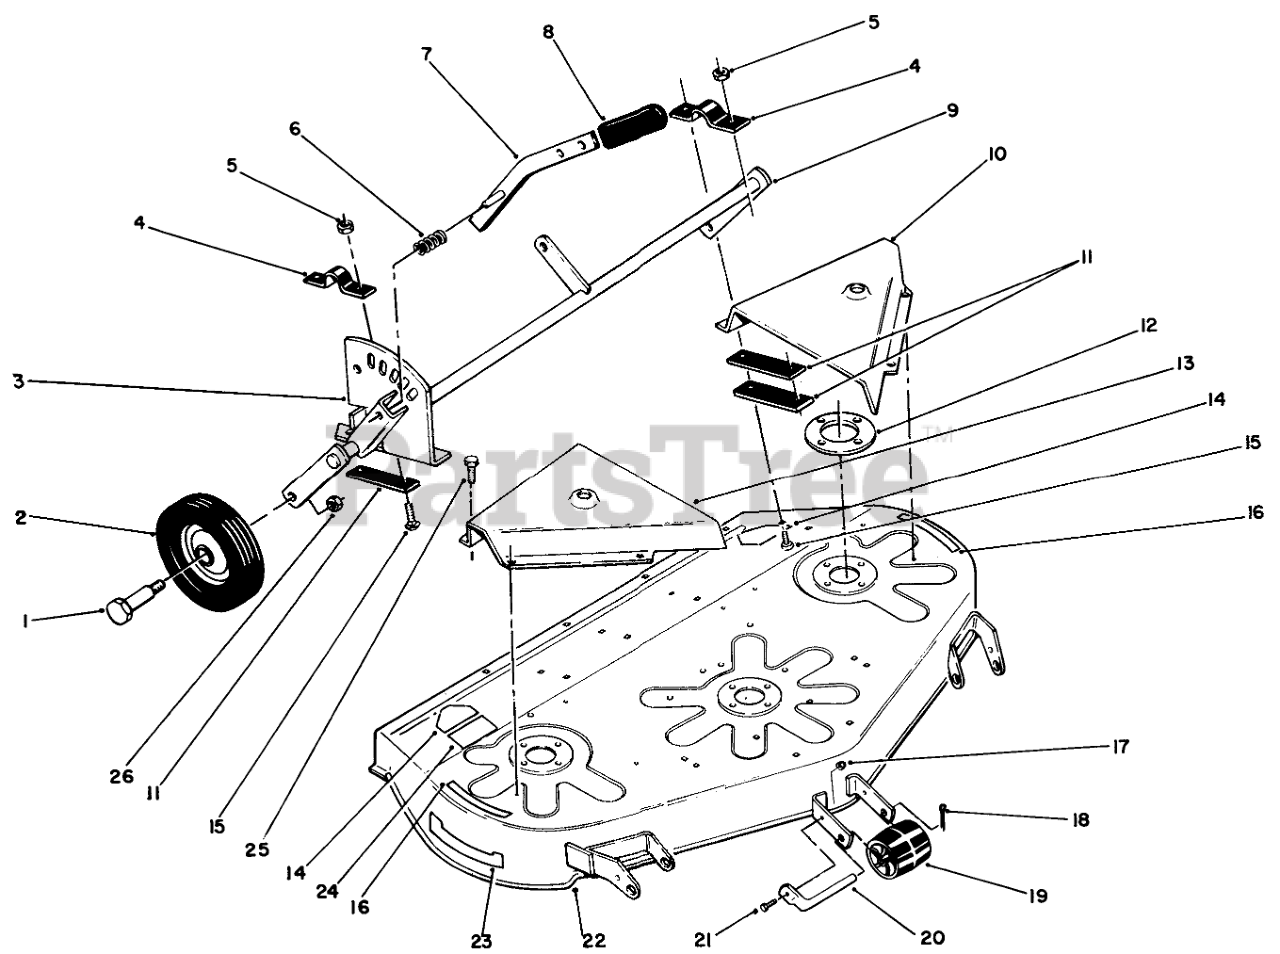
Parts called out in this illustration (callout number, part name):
1	BOLT-SHOULDER
2	WHEEL
3	Quadrant
5	NUT
6	SPRING-COMPRESSION
7	Lever
9	Gage Wheel Support
10	Belt Cover LH
11	Bar
12	Plate-Spindle
13	Belt Cover RH
14	DECAL-DANGER
15	Bolt
16	DECAL - DANGER
17	Nut
18	Cotter Pin
19	Roller
20	ROLLER-SHAFT
21	Bolt
22	Deck-Mower
23	DECAL-42" RECYCLER
24	DECAL-HEIGHT & BELT
25	Bolt
26	Nut
